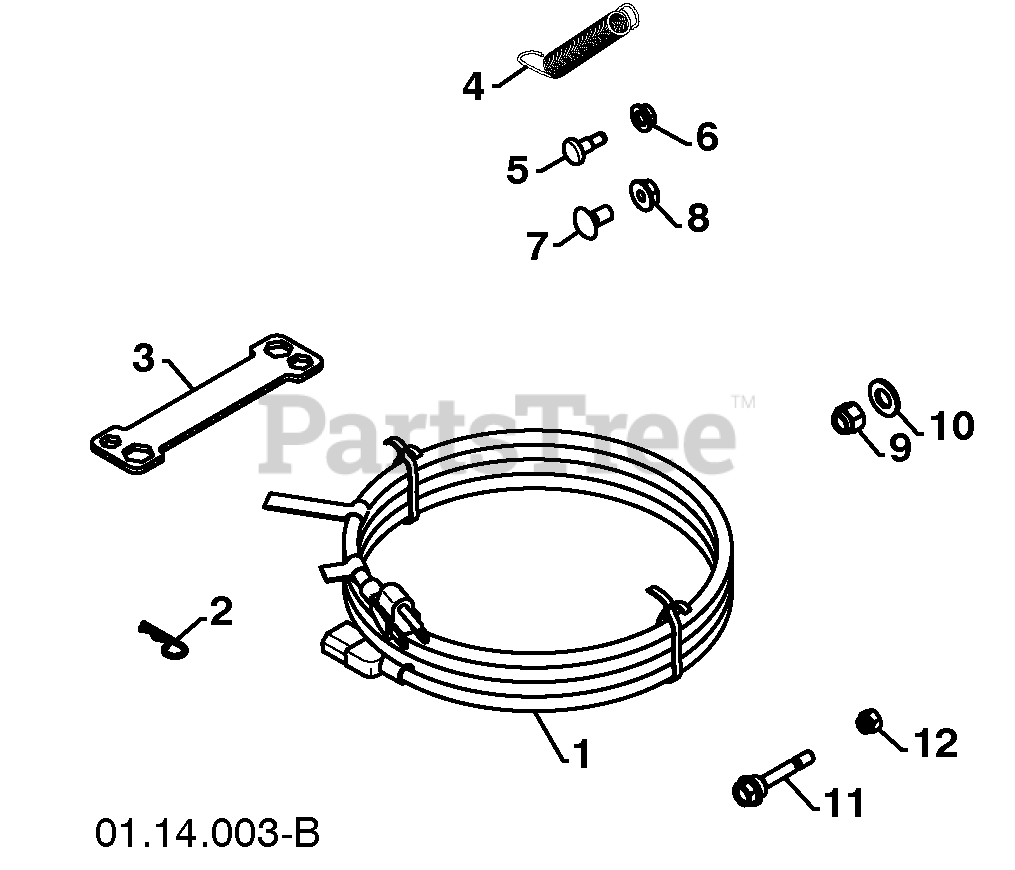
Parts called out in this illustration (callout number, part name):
1	POWER CORD
2	RETAINER PIN
4	REMOTE SPRING
5	SHOULDER BOLT 1/4-20
6	LOCKNUT 1/4-20
7	CARRIAGE BOLT 5/16-18 X 5/8
8	LOCKNUT 5/16-18
9	LOCKNUT 3/8-16
10	WASHER 3/8
11	SHEAR BOLT 1/4-20 X 1-13/16
12	LOCKNUT 1/4-20
